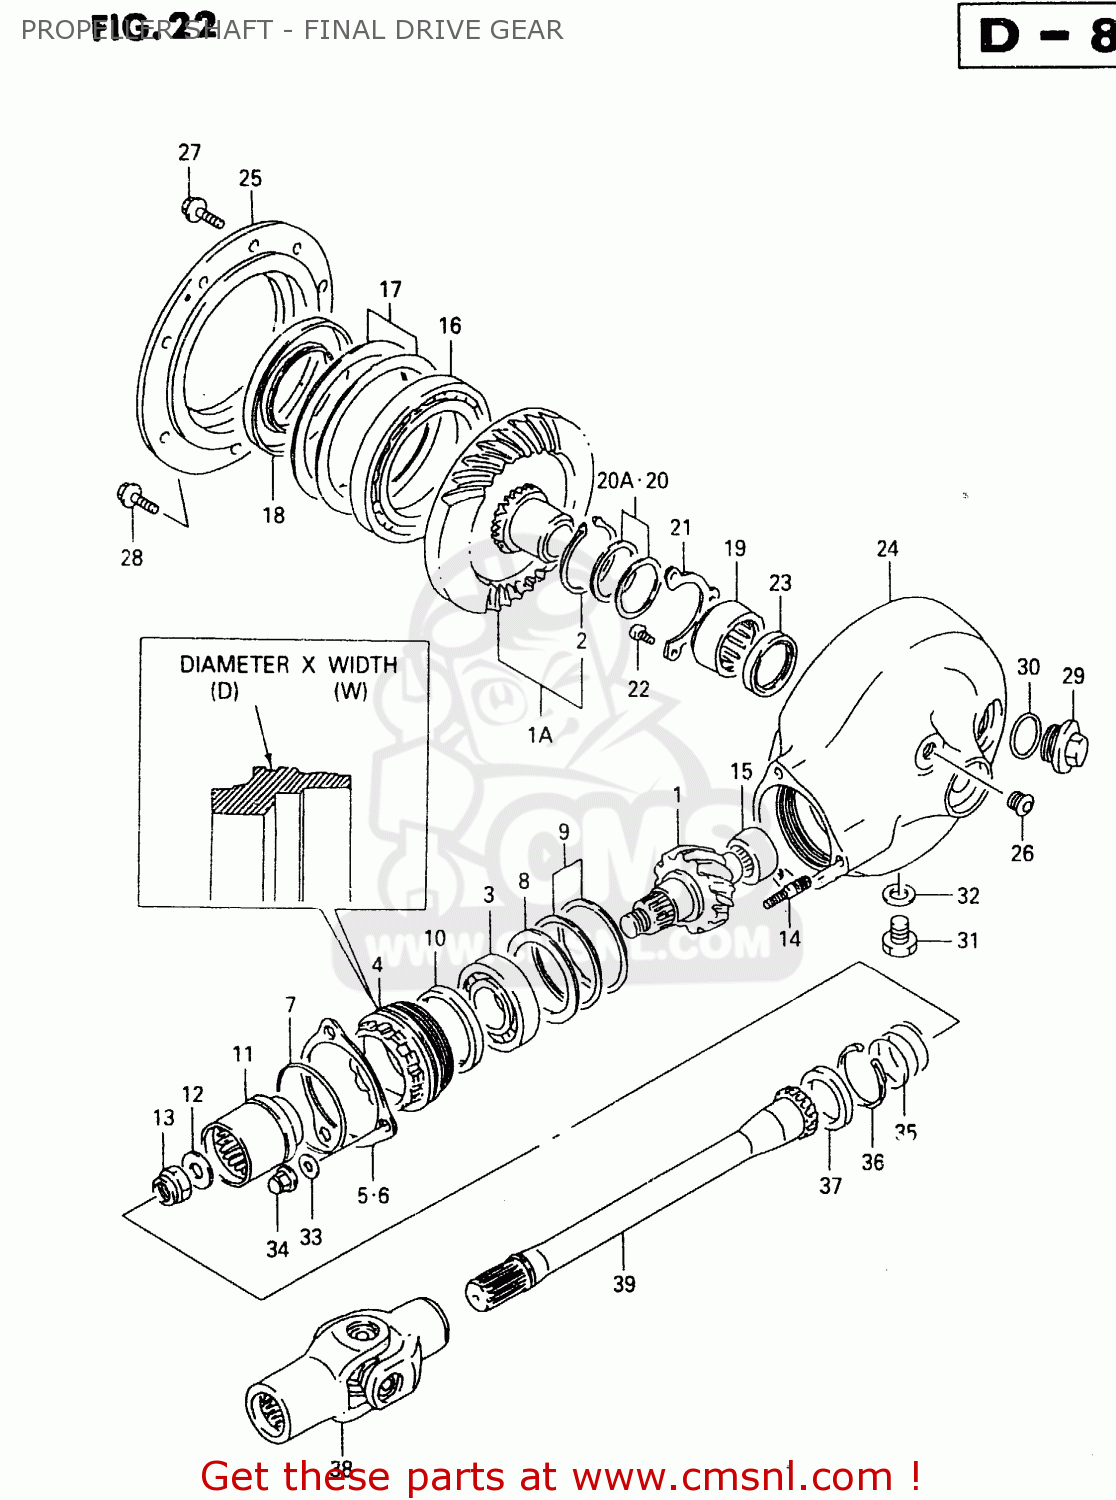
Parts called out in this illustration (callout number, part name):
1	GEAR,FINAL DRIVE BEVEL
1A	GEAR,FINAL DRIVEN BEVEL
2	.CIRCLIP
3	BEARING(28X68X18)
4	STOPPER,FINAL DRIVE BEARING
5	PLATE,BEARING STOPPER
6	PLATE,BEARING STOPPER
7	O RING(D:3.1,ID:63.9)
8	WASHER(54X68X1.5)
9	SHIM SET,FINAL DRIVE GEAR
10	SEAL,OIL
11	COUPLING,FINAL DRIVE GEAR
12	WASHER(16X29X4)
13	NUT
14	STUD 10X25
15	BEARING(20X34X18)
16	BEARING(85X130X14)
17	SHIM SET,FINAL DRIVEN GEAR
18	SEAL,OIL(70X110X14.7)
19	BEARING(35X48X23.7)
20	WASHER(35X46X0.95)
20A	SHIM SET,FINAL DRIVEN GEAR
21	RETAINER,FINAL DRIVEN GEAR BRG
22	SCREW
23	SEAL,OIL(35X43X5)
24	CASE,FINAL GEAR
25	CASE,FINAL GEAR BEARING
26	PLUG
27	BOLT
28	BOLT
29	PLUG,30X9
30	O RING(D:3.1,ID:26.4)
31	PLUG
32	GASKET(13.8X18.8X4.8) (NAS)
33	WASHER
34	NUT
35	SPRING
36	CIRCLIP
37	SEAL,OIL(30X40.5X5.5)
38	YOKE COMP,UNIVERSAL JOINT
39	SHAFT,PROPELLER
